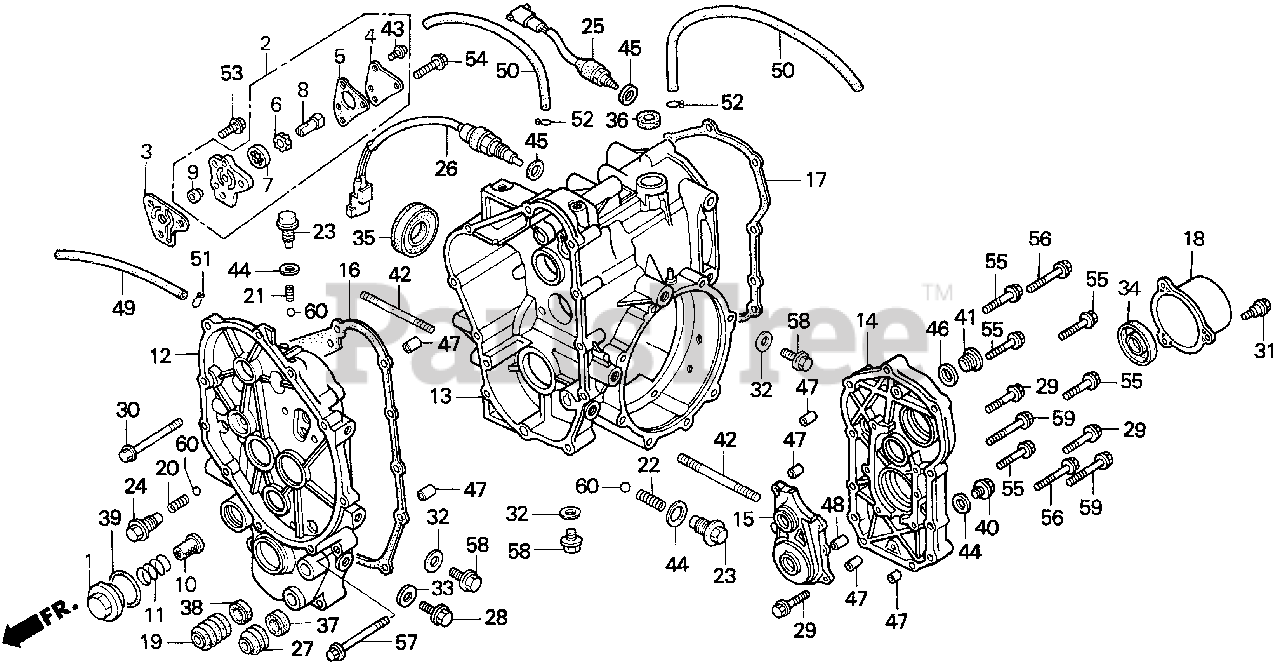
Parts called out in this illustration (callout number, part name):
1	CAP, VALVE ADJ.
2	PUMP ASSY., OIL
3	GASKET, OIL PUMP BODY
4	COVER, OIL PUMP
5	GASKET, OIL PUMP COVER
6	ROTOR, OIL PUMP (INNER) (YAMADA)
7	ROTOR, OIL PUMP (OUTER) (YAMADA)
8	SHAFT, OIL PUMP DRIVE
9	PIN, OIL PUMP KNOCK (NOT AVAILABLE)
10	SCREEN, OIL FILTER
11	SPRING, OIL FILTER SCREEN
12	CASE, FR. TRANSMISSION
13	CASE, RR. TRANSMISSION
14	COVER, RR. TRANSMISSION
15	CASE, P.T.O. REDUCTION
16	GASKET, TRANSMISSION CASE
17	GASKET, RR. COVER
18	COVER, P.T.O.
19	BOOT, SHIFT SHAFT
20	SPRING, SET BALL INTERLOCK
21	SPRING, BALL SETTING (NOT AVAILABLE)
22	SPRING, BALL SETTING
23	SCREW, BALL SPRING SETTING
24	SCREW, BALL SPRING SETTING
25	SWITCH ASSY., RR. P.T.O.
26	SWITCH ASSY., NEUTRAL
29	BOLT, FLANGE (8X40) (SEALING)
30	BOLT, FLANGE (8X45)
31	BOLT, SPECIAL (6MM)
32	WASHER, PLAIN (10MM)
34	OIL SEAL (40X62X8)
35	OIL SEAL (26X48X7.8)
36	OIL SEAL (12X22X6)
38	OIL SEAL (14X24X11.5)
39	O-RING (35X3)
40	BOLT, DRAIN PLUG (12MM)
41	BOLT, DRAIN PLUG (20MM)
42	BOLT, STUD (10X80)
43	SCREW-WASHER (5X10)
44	WASHER, DRAIN PLUG (12MM)
45	WASHER, DRAIN PLUG (14MM)
46	WASHER, DRAIN PLUG (20MM)
47	PIN A, DOWEL (10X16)
48	PIN C, DOWEL (8X14)
49	BULK HOSE, FUEL (4.5X3000) (4.5X260)
50	BULK HOSE, FUEL (5.5X3000) (5.5X380)
51	CLIP, TUBE (B8)
52	CLIP, TUBE (B10)
53	BOLT, FLANGE (6X18)
54	BOLT, FLANGE (6X25)
55	BOLT, FLANGE (8X40)
56	BOLT, FLANGE (8X50)
57	BOLT, FLANGE (8X90)
58	BOLT, FLANGE (10X25)
59	BOLT, FLANGE (10X50)
60	BALL, STEEL (#10) (5/16)
